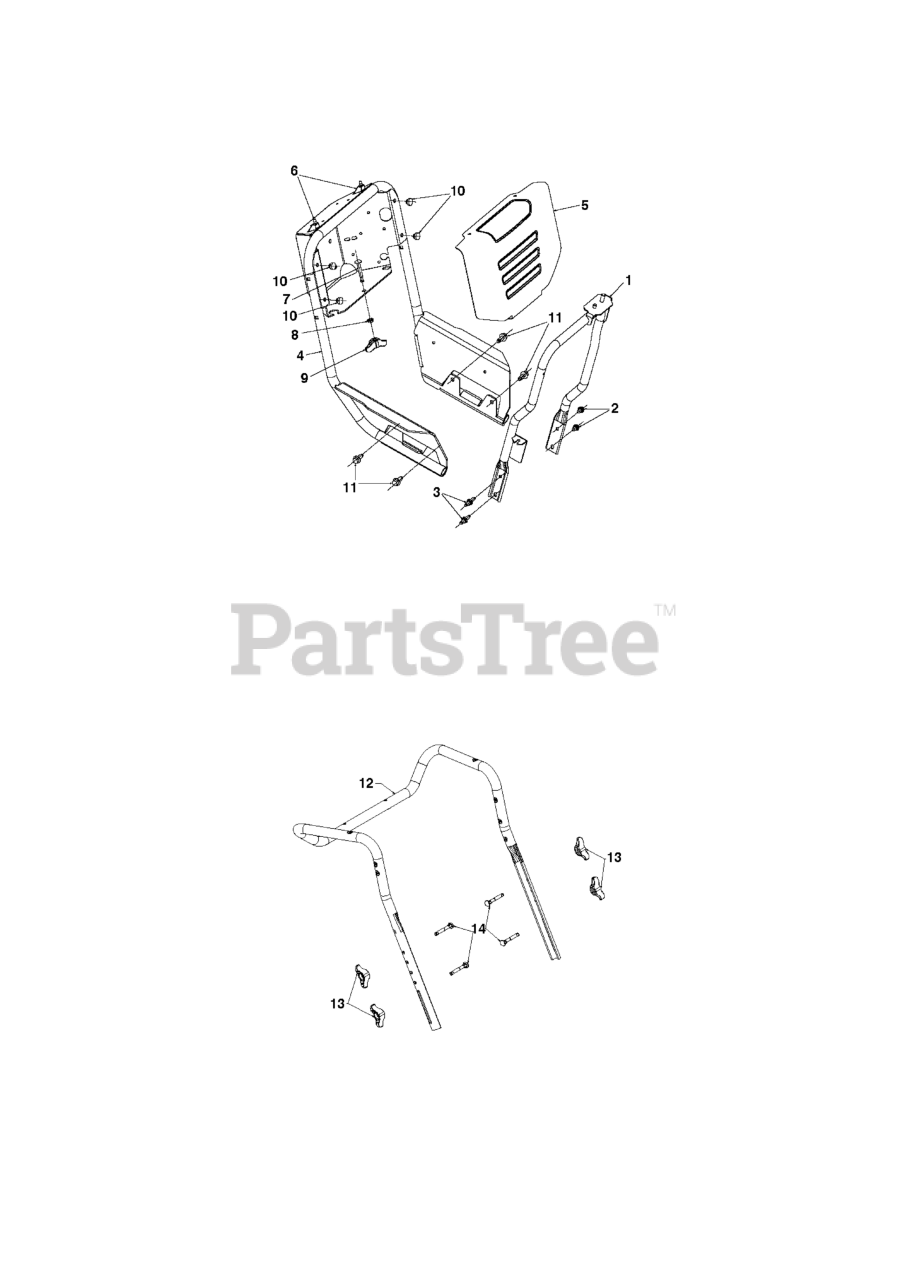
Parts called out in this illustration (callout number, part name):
1	SUPPORT WELDMENT, CHUTE PAINTE
2	BOLT.5/16HEX.WHS.HD
3	STUD BOLTED HEX HEAD
7	BOLT.HAND.PIV.ADJ.313-18.21EFF
8	GSPW Hardware
10	GROMMET.BUMPER
11	SCREW HEXAGON HEAD FLANGE 3/8-
12	HANDLE.UPPER.498
13	KNOB, DEFLECTOR
14	BOLT.CARRIAGE.5/16-18 X 2.25
